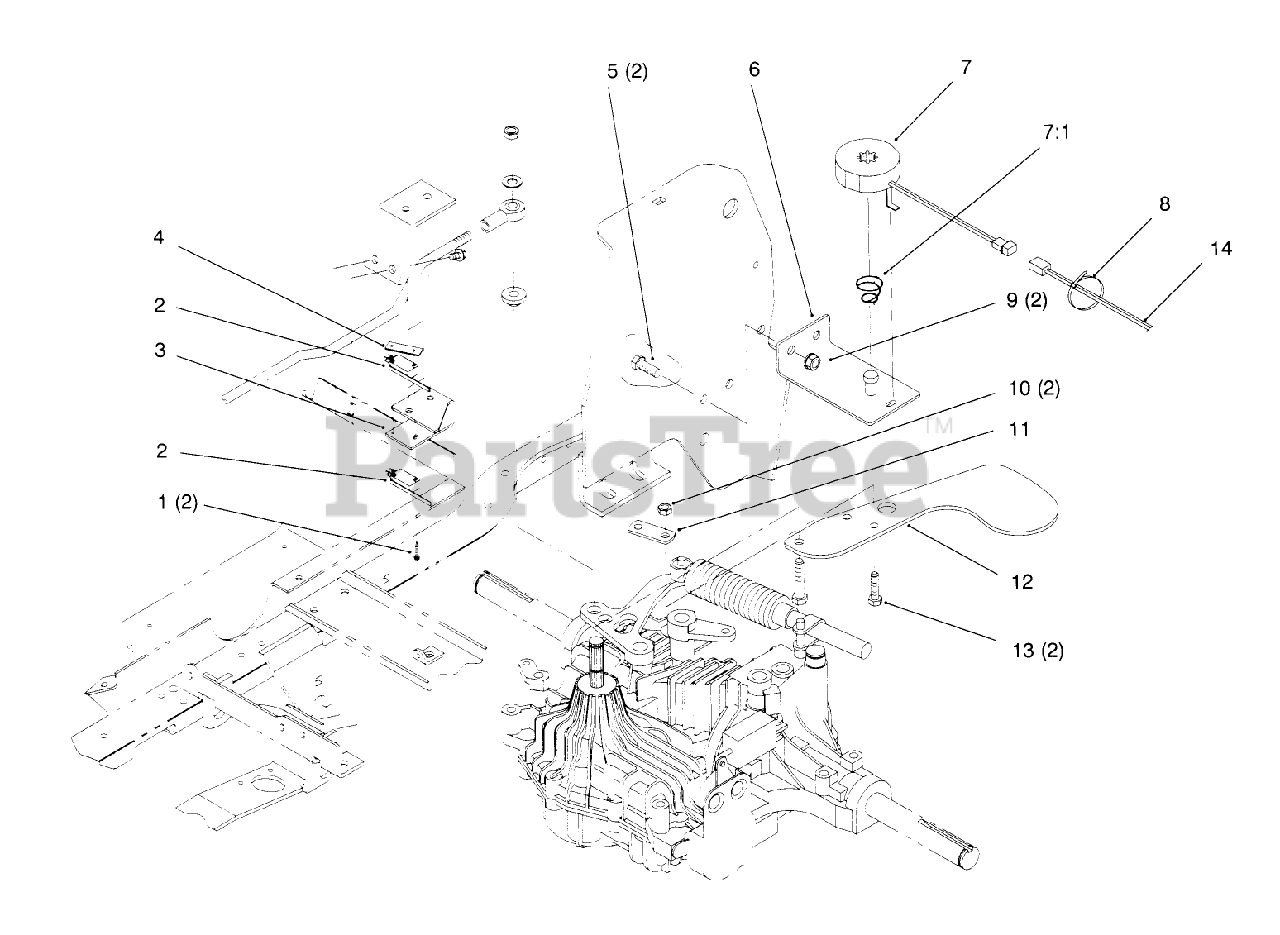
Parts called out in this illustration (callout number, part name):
1	SCREW-HH
2	SWITCH-MICRO
3	BRACKET-BRAKE SWITCH
4	NUT-SPEED
5	SCREW-HH
7:1	SPRING-COMPRESSION
8	TIE-CABLE
9	NUT-LOCK, NI
10	NUT-LOCK, NI
11	CLAMP - CRUISE
12	ARM - CRUISE
13	SCREW-HH
